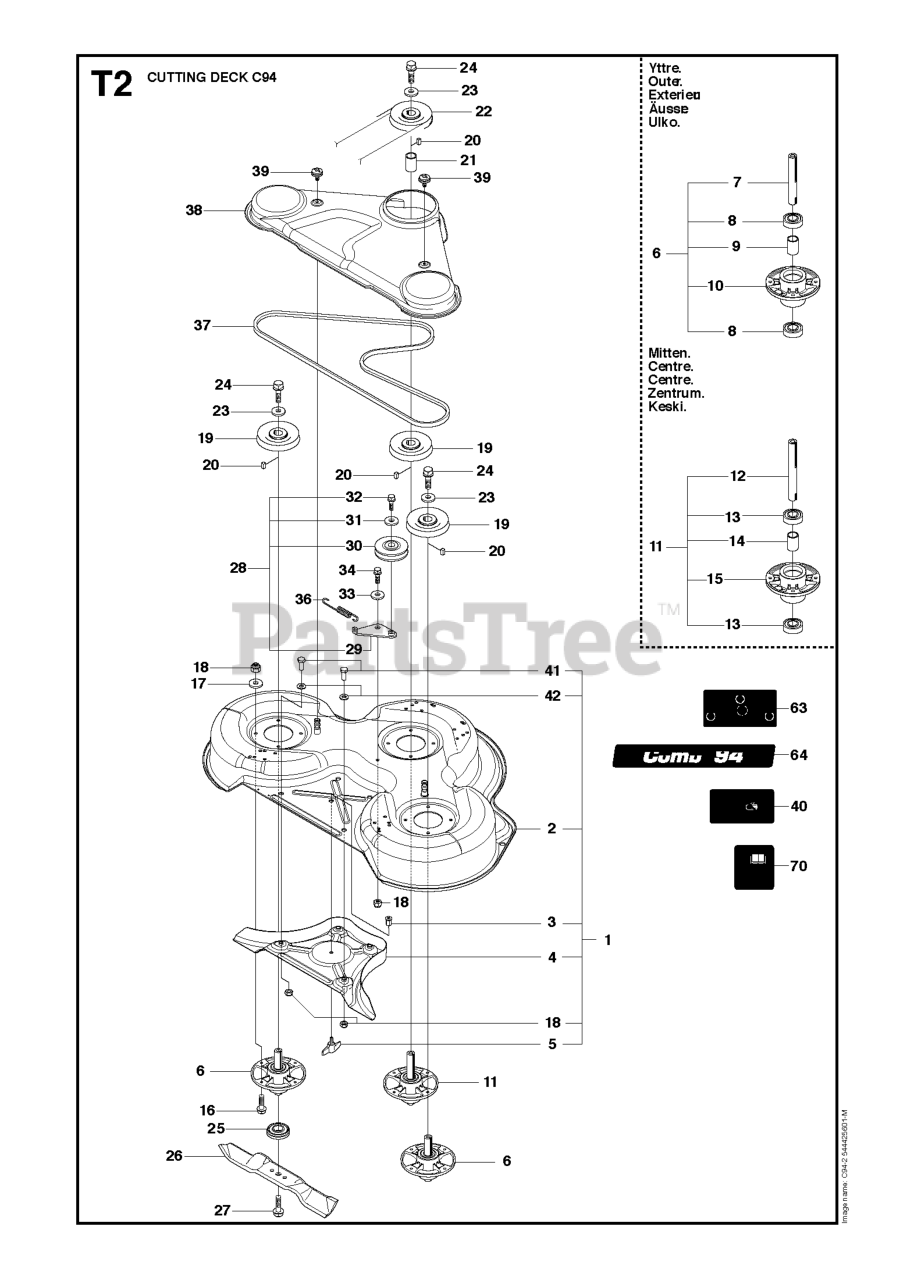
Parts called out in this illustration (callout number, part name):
4	PLUG C93 & C94
6	BLADE HOUSING ASSY
9	SPACING SLEEVE
10	BEARING HOUSING
14	SPACING SLEEVE
15	BEARING HOUSING
17	WASHER BRB 8.4X17
18	LOCKNUT M8
21	SPACING SLEEVE
25	BLADE BRACKET
30	PULLEY
33	WASHER
42	WASHER BRB 8.4X17
